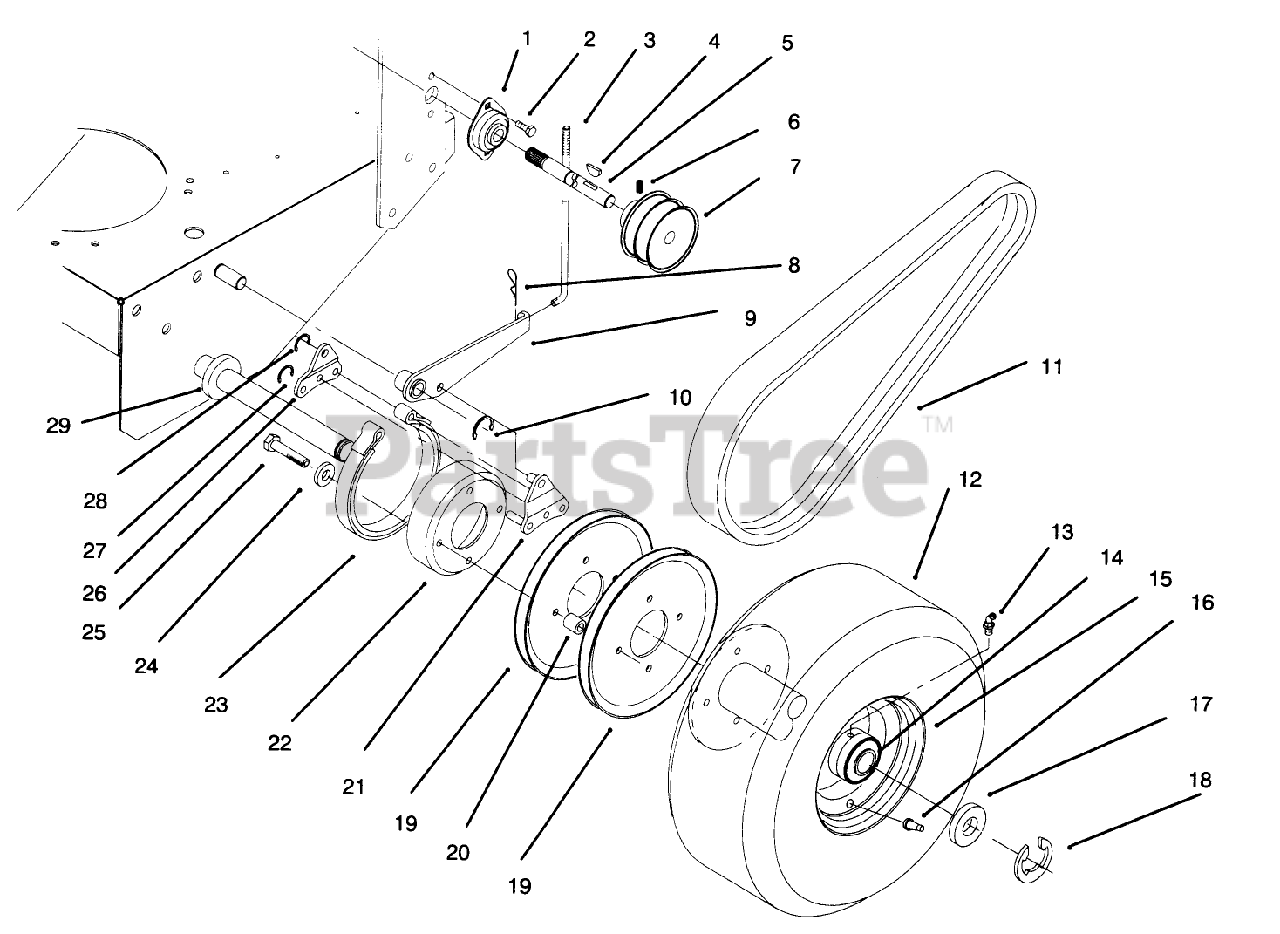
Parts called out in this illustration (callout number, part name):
1	BEARING-EXTERNAL SHAFT
2	SCREW-HH
3	ROD-BRAKE
4	KEY-WOODRUFF
5	SHAFT-EXTENSION, RH
6	SCREW-SET, HS
7	Pulley-Drive
8	PIN-COTTER
9	Brake Arm-LH
10	RING-RETAINING
11	V-BELT
13	FITTING-LUBE, 45 DEG
14	BEARING-BALL
15	WHEEL AND HUB ASM
16	STEM-VALVE
17	WASHER-THRUST
18	RING-RETAINING
19	Pulley-Wheel
20	SPACER-PULLEY
21	LINK-Brake
22	Drum-Brake
23	BAND-BRAKE
24	WASHER-LOCK
25	SCREW-HH
26	Plate-Link
27	RING-RETAINING
28	RING-RETAINING, EXTERNAL
29	WASHER-WHEEL
